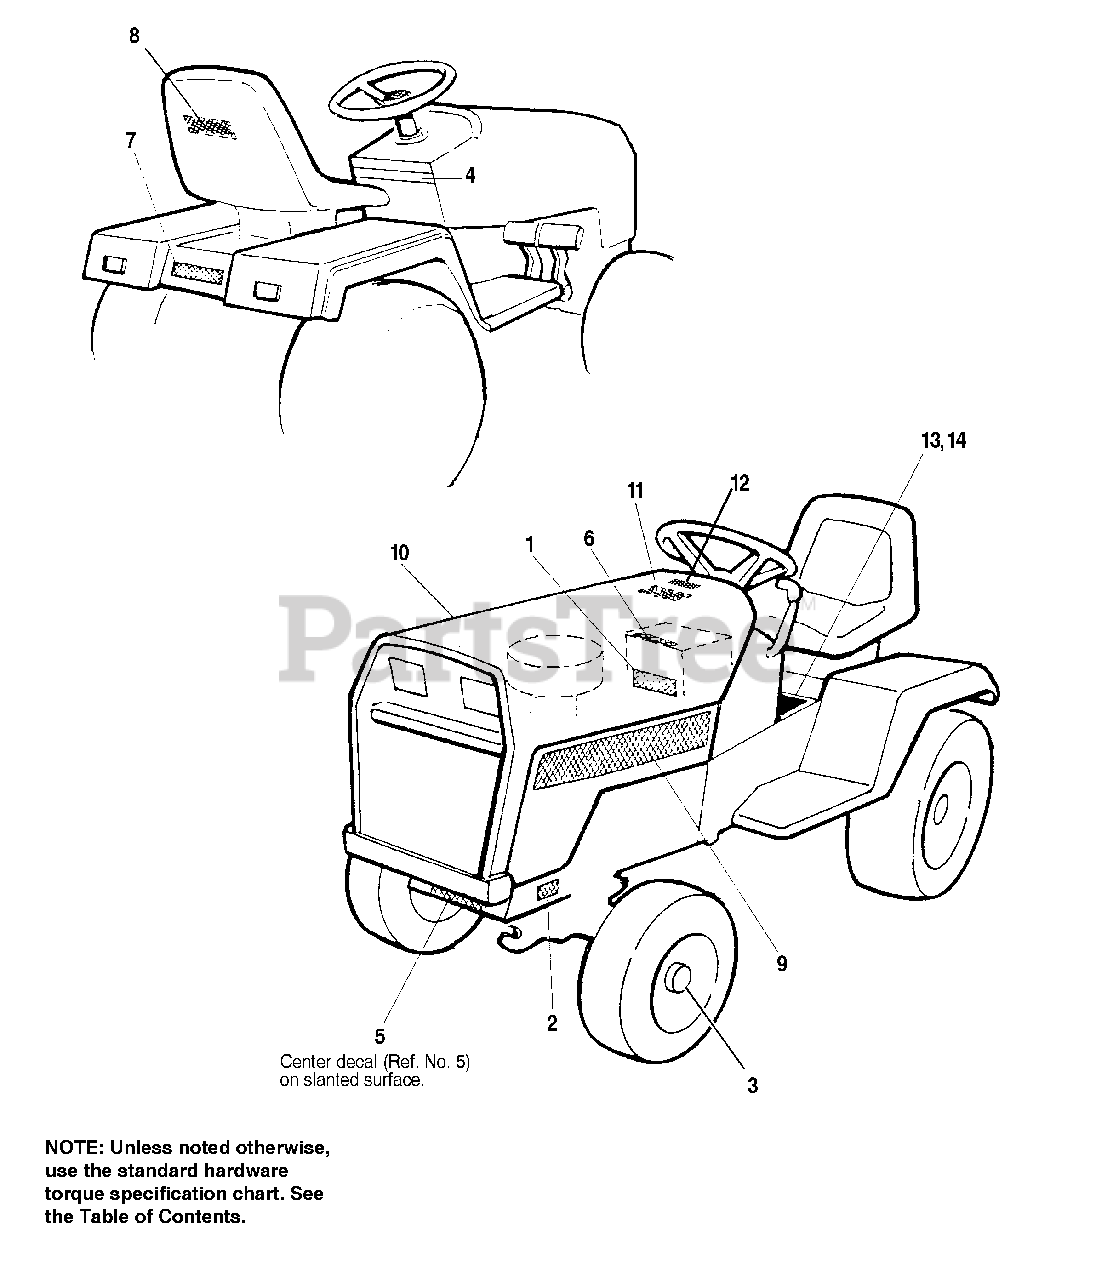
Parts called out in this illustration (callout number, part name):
1	DECAL, Battery
2	I.D. PLATE
3	DECAL, Hub Cap
4	DECAL, Panel, Rear Dash (Choke, lgnition, etc.)
5	DECAL, Warning, Front PTO Shield
6	DECAL, Warning (Disconnect Elect. Ground, etc.)
7	DECAL, Rear Logo, AGCO Allis
8	DECAL, USA Logo
9	DECAL, Hood, LH 20HP
10	DECAL, Hood, RH 20HP
11	DECAL, Touch-up Paint
12	DECAL, Belts/Blade Replacement
13	DECAL, Tunnel Cover
14	DECAL, Tunnel Cover
